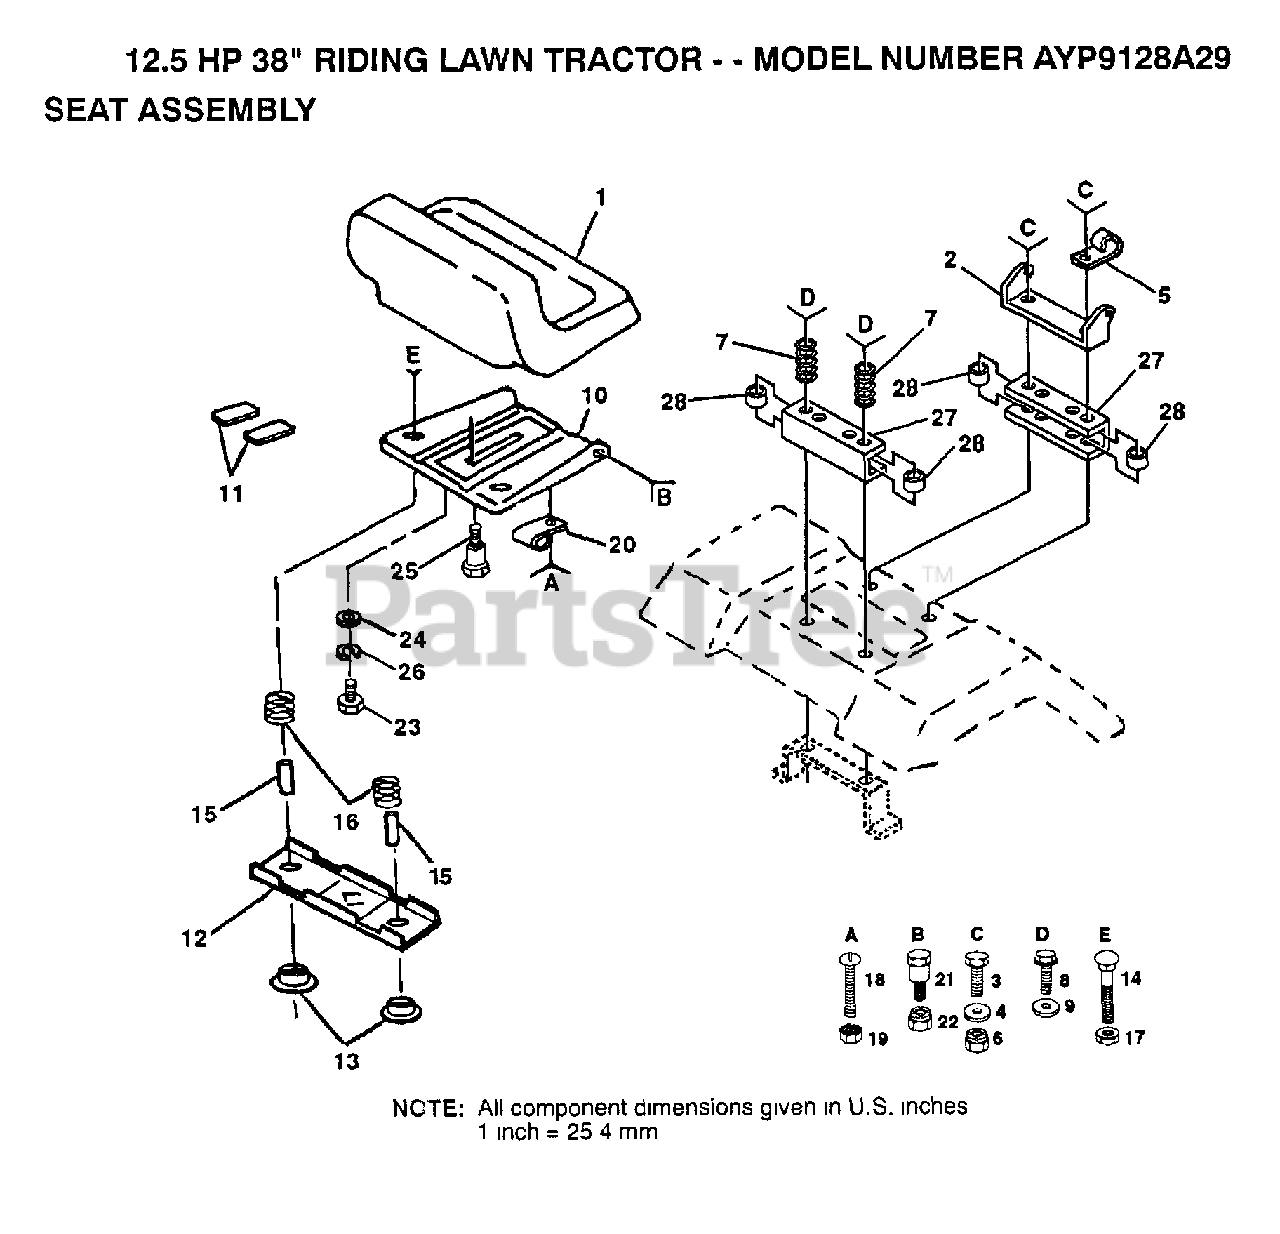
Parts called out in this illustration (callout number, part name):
3	BOLT
4	WASHER
5	CLIP T
7	SPRING COMPRESSIO
8	SCREW
9	WASHER
11	STRIP FORM
12	BRKT SWITCH
13	BUSHING
15	SPACER SPLIT
16	SPRING
19	"NUT,KEPS"
21	BOLT SHOULDER
23	BOLT
24	WASHER
25	"BOLT,SHOULDER"
26	LOCKWASHER
27	SEAT SPACER
28	SPLIT SPACER
